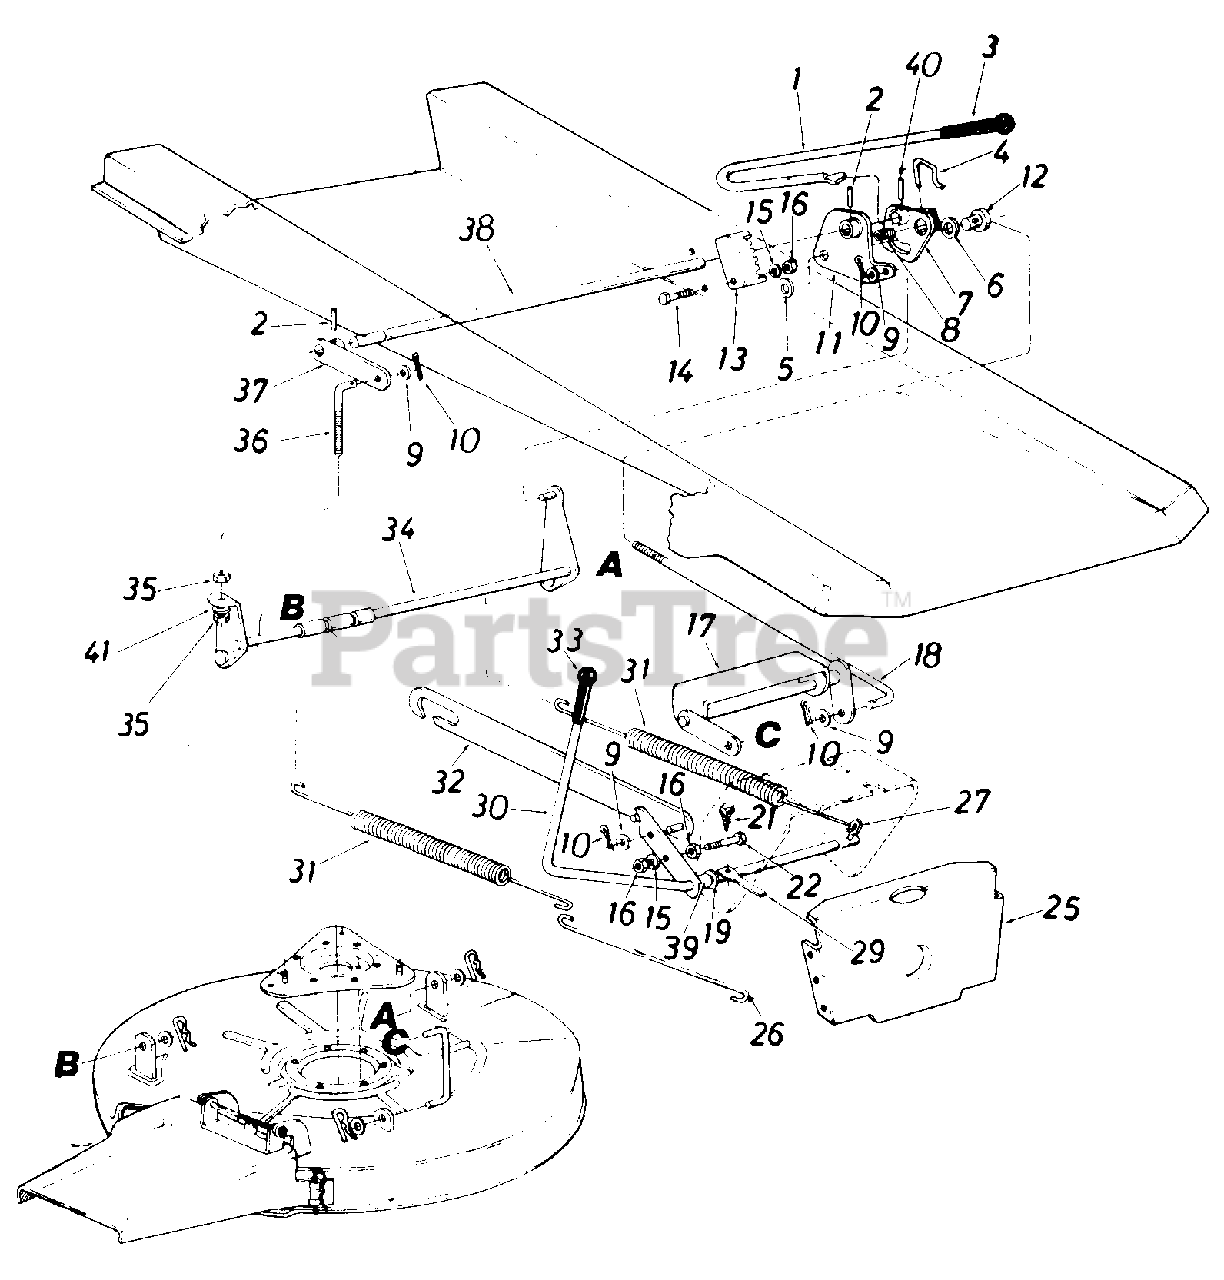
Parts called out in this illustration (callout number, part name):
1	Deck Lift Handle
2	Spring Pin Spir. 1/4" Dia. x 1.50" Lg.
4	Cotter Pin
5	Fl-Wash. 5/8" I.D. x 1.0" O.D. x .1 2
6	Fl-Wash. 5/8" I.D. x 1.25" O.D. x .60
7	Deck Lift Handle Brkt. Ass'y.
8	Compression Spring .50" O.D. x 1.04
9	Fl-Wash. .385" I.D. x .87" O.D. x .06
10	Cotter Pin 1/8" Dia. x 1.00"*
11	Deck Lift Brkt. Ass'y. L.H.
12	Adj. Ferrule Deck Lift Handle
13	Index Bracket
14	Hex Bolt 5/16-18 x .75" Lg.*
15	L-Wash. 5/16" I.D.*
16	Hex Nut 5/16-18 Thd.*
17	Deck Lift Ass'y. Front
18	Deck Lift Connecting Rod
19	Fl-Wash. .531" I.D. x .930"
21	Hex Wash. Hd. Self-Tap Scr. 1/4-20 x .50" Lg.
22	Hex Bolt 5/16-18 x 1.50" Lg.*
25	Pivot Bar Bracket
26	Spring Hook
27	Spec. Clevis Pin .250" Dia.
29	Switch Actuator
30	Blade Engagement Lever Ass'y.
31	Extension Spring .99" O.D. x 14.25" Lg.
32	Deck Drive Control Brkt. Ass'y.
34	Deck Link Ass'y. Rear
35	Hex Nut 3/8-16 Thd.
36	Deck Adj. Scr. 3/8-16 Thd.
37	Deck Lift Brkt. Ass'y. R.H.
38	Rear Height Adj. Shaft
39	Sleeve .511" I.D. x .70" O.D. x.37" Lg.
40	Spring Pin Spir. 3/16" Dia. x 1.50" Lg.
41	L-Wash. 3/8" I.D.*
